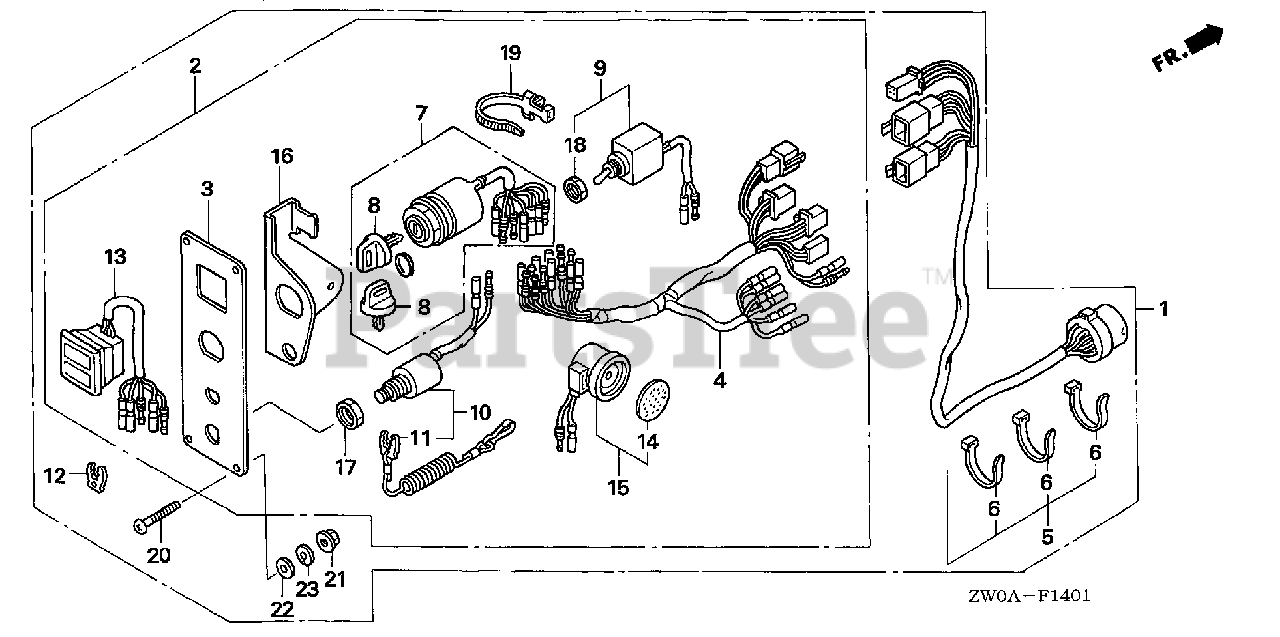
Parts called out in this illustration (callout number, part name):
1	PANEL KIT, SWITCH (DUAL)
2	PANEL ASSY., CONTROL
3	PANEL, CONTROL
4	HARNESS ASSY., SWITCH PANEL
5	CABLE ASSY., SWITCH PANEL
6	TIE, CABLE (NATURAL 2.4X92)
7	SWITCH ASSY., COMBINATION
8	KEY ASSY., COMBINATION SWITCH
9	SWITCH ASSY., SOLENOID
10	SWITCH ASSY., EMERGENCY STOP
11	WIRE, EMERGENCY
12	CLIP, EMERGENCY LOCK
13	LAMP ASSY., INDICATION (2-LED)
14	PLATE, TURN SIGNAL BUZZER
15	BUZZER, WARNING
16	BRACKET, BUZZER
17	NUT, HEX. (16MM)
18	NUT, HEX. (12MM)
19	BAND, WIRE HARNESS (150MM)
20	SCREW, PAN (5X40)
21	NUT, FLANGE (5MM)
22	WASHER, PLAIN (5MM)
23	WASHER, SPRING (5MM)
